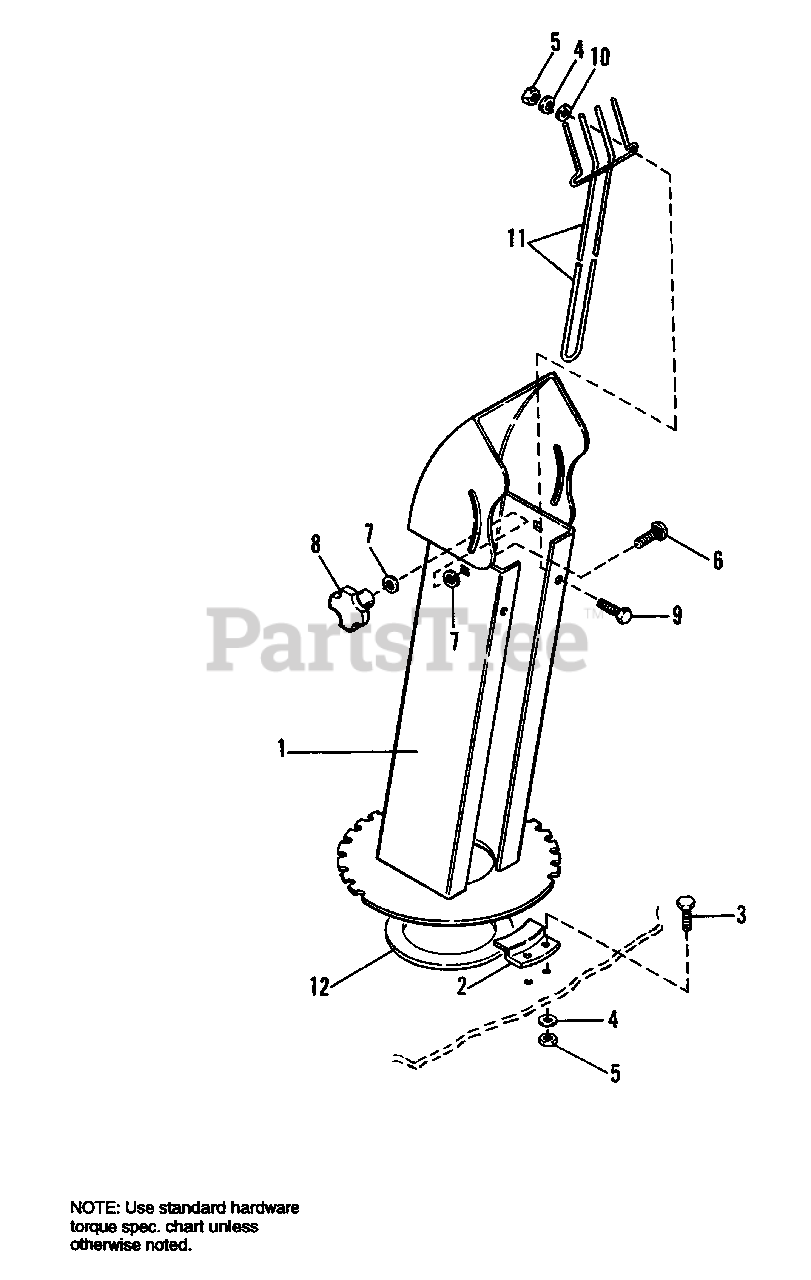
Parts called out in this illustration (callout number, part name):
1	CHUTE, 47" Snowblower
2	RETAINER, Chute
3	CAPSCREW, Hex Hd., 1/4-20 x 1/2
4	LOCKWASHER, 1/4 regular
5	NUT, Hex, 1/4-20
6	CARRIAGE BOLT, 5/16-18 x 3/4
7	WASHER, Flat, 7/8 OD x 11/32 ID x 1/16
8	KNOB, Hand
9	CAPSCREW, Hex Hd., 1/4-20 x 1
10	WASHER, Flat, 1/4 SAE
11	GUARD, Chute
12	GASKET, Chute
